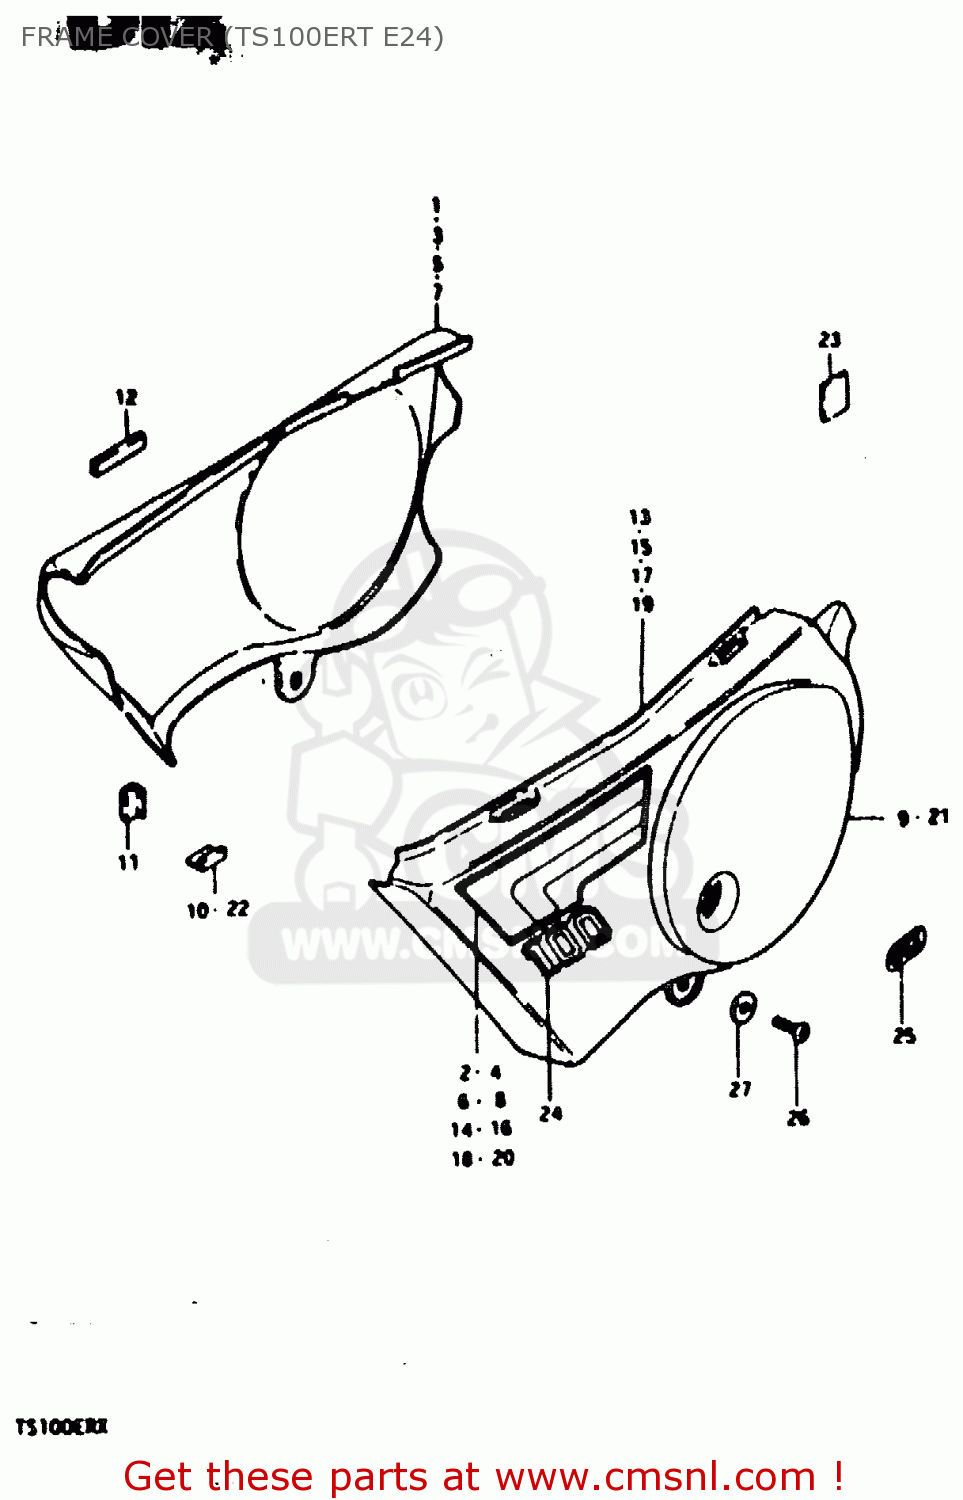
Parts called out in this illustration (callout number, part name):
1	COVER, FRAME RH (RED)
2	TAPE, RH
3	COVER, FRAME RH (WHITE)
4	TAPE, RH
5	COVER, FRAME RH (BLUE)
6	TAPE, RH
7	COVER, FRAME RH (YELLOW)
8	TAPE, RH
9	EMBLEM, RH
10	CUSHION,FRAME COVER
11	CUSHION,FRAME COVER
12	CUSHION,FRAME COVER
13	COVER, FRAME LH (RED)
14	TAPE, LH
15	COVER, FRAME LH (WHITE)
16	TAPE, LH
17	COVER, FRAME LH (BLUE)
18	TAPE, LH
19	COVER, FRAME LH (YELLOW)
20	TAPE, LH
21	EMBLEM, LH
22	CUSHION,FRAME COVER
23	PROTECTOR(170X95X3.0)
24	EMBLEM
25	EMBLEM,CCIS
26	SCREW 6X12
27	WASHER
